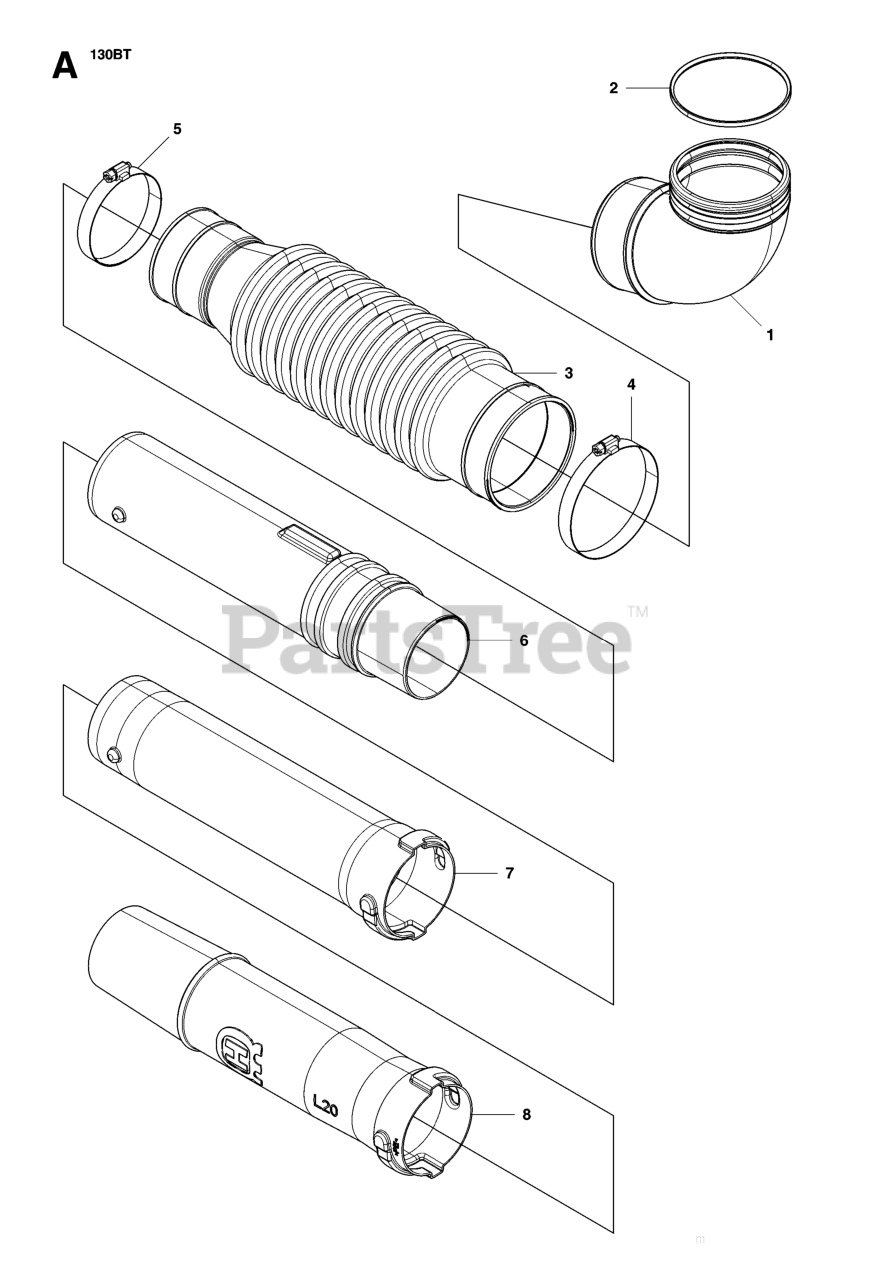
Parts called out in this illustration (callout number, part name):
2	O-RING
5	CLAMP(F96)
6	SWIVEL JOINT
7	PIPE STRAIGHT
